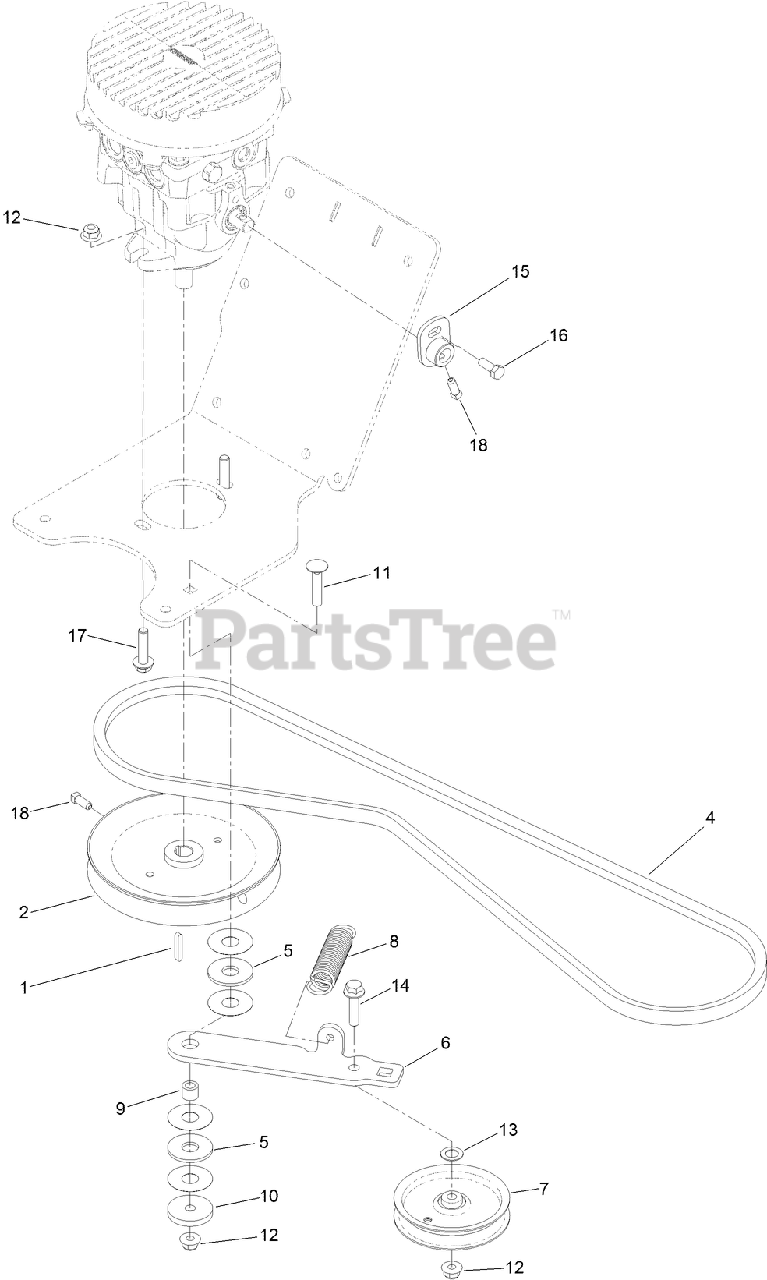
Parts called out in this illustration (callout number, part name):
2	PULLEY W/HUB
4	V-BELT, PTO
5	WASHER-FRICTION, COMPOSITE
6	ARM-IDLER
7	PULLEY-IDLER
8	SPRING-BRAKE, MAIN
9	BUSHING-LEVER, LIFT
10	WASHER-PLAIN
11	SCREW-CARR
12	NUT-HF, NI
13	WASHER-THRUST
14	SCREW-HHF
15	CONTROL ARM ASM
16	SCREW-HH
17	SCREW-HHF
18	SCREW-SET, SQH
